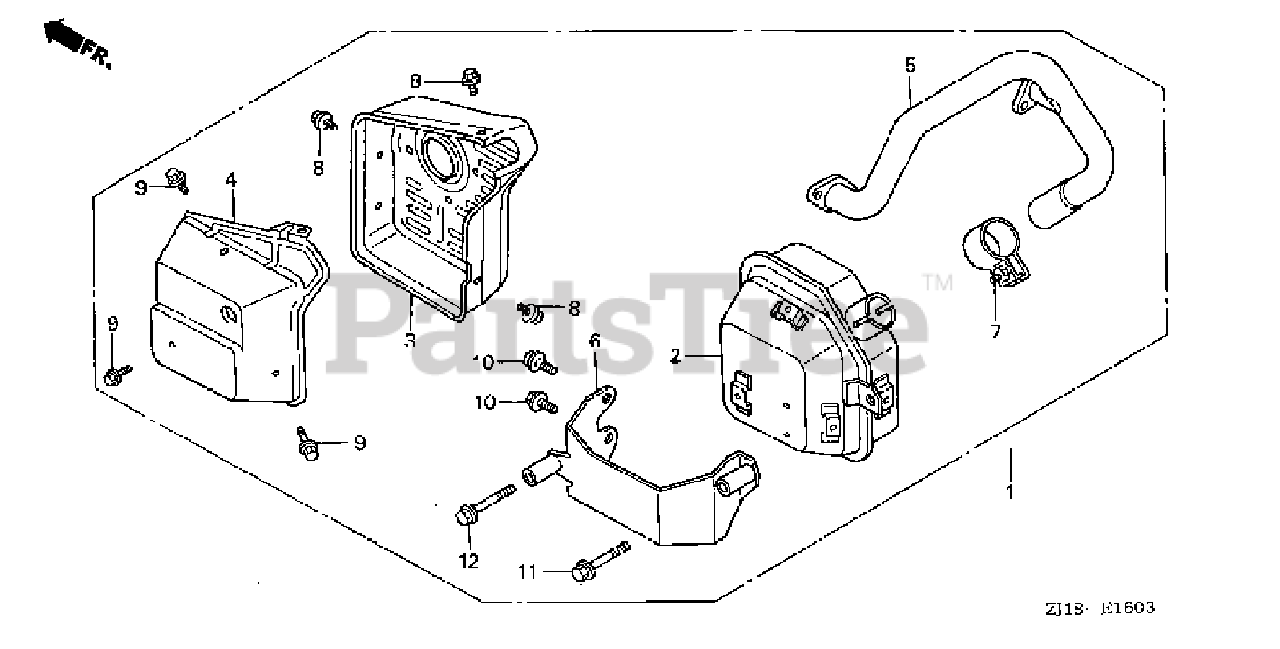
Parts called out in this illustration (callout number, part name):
1	MUFFLER KIT (SIDE-L) (N/A: SEE COMPONENTS)
2	MUFFLER (SIDE-L)
3	PROTECTOR, MUFFLER (SIDE-L)
4	PROTECTOR, RR. MUFFLER (SIDE-L)
5	PIPE, EX. (SIDE-L)
6	STAY, MUFFLER (SIDE-L)
7	BAND ASSY.
8	SCREW, PAN (6X8)
9	BOLT, FLANGE (6X8)
10	BOLT, FLANGE (8X14)
11	BOLT, FLANGE (8X55)
12	BOLT, FLANGE (8X55)
